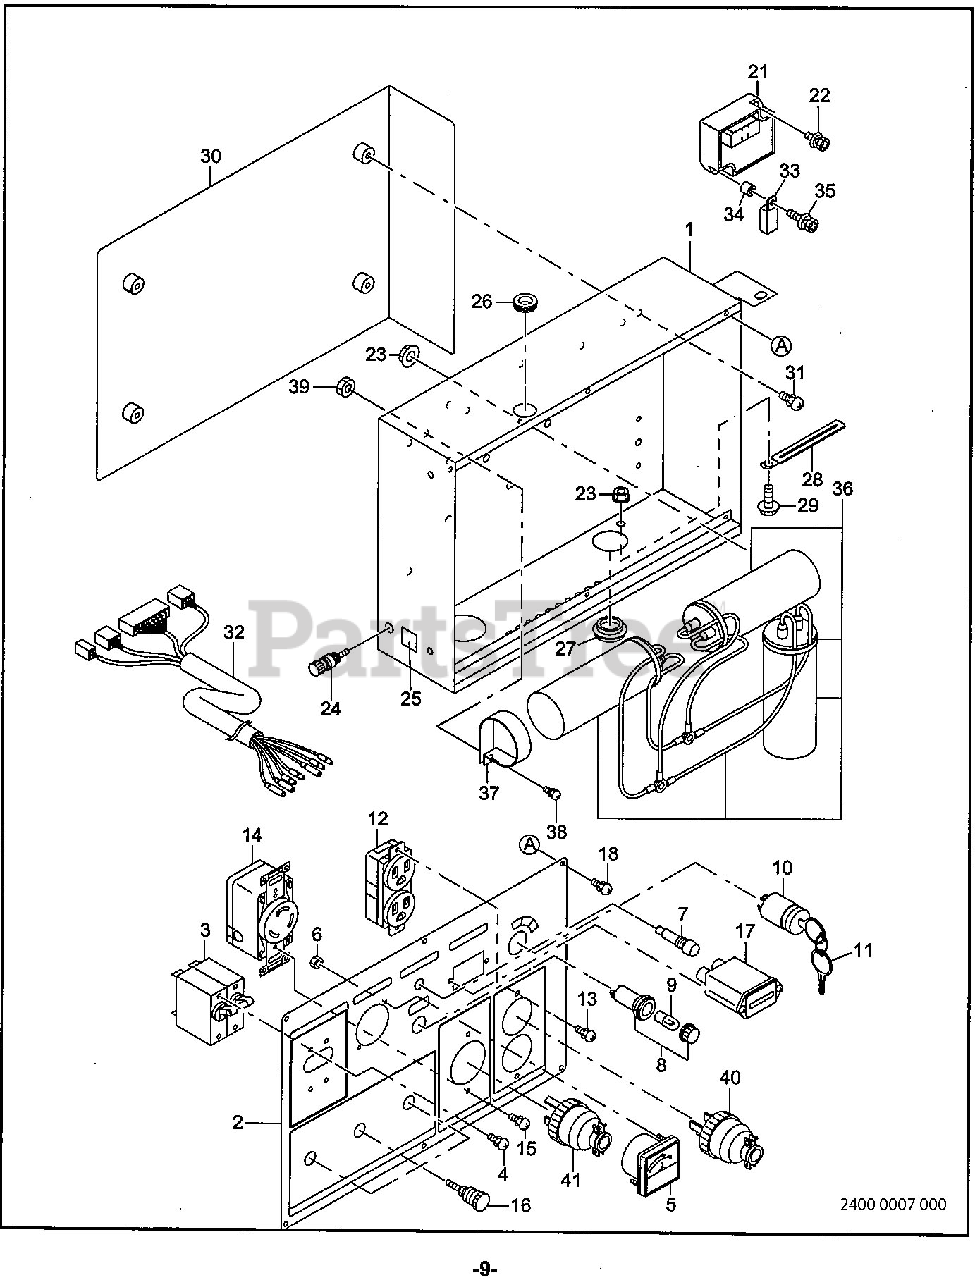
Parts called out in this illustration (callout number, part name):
1	CONTROL BOX ASSY
1	CONTROL BOX UNIT
2	CONTROL PANEL ASSY
2	CONTROL PANEL
3	BREAKER (2P-37A) For 60Hz-120V/240V
3	BREAKER (2P-40A) For 60Hz-110V/220V
4	SCREW and WASHER ASS
8	LAMP (OIL)
9	LAMP (18V-0.11A)
10	KEY SWITCH
12	AC RECEPTACLE (125V-15A)
13	SCREW and WASHER ASSY
14	AC RECEPTACLE (250V-30A, TWIST LOCK)
15	SCREW and WASHER ASSY
16	TERMINAL
18	SCREW and WASHER ASS
21	ECU(O/S & R/C) ASSY
22	SCREW and WASHER ASSY
23	FLANGE NUT
29	FLANGE BOLT
31	SCREW and WASHER ASSY
32	WIRE ASSY
35	SCREW
36	CONDENSER ASSY
37	CONDENSER BRACKET
38	SCREW and WASHER ASSY
40	AC PLUG (250V-15A)
41	AC PLUG (250V-30A)
